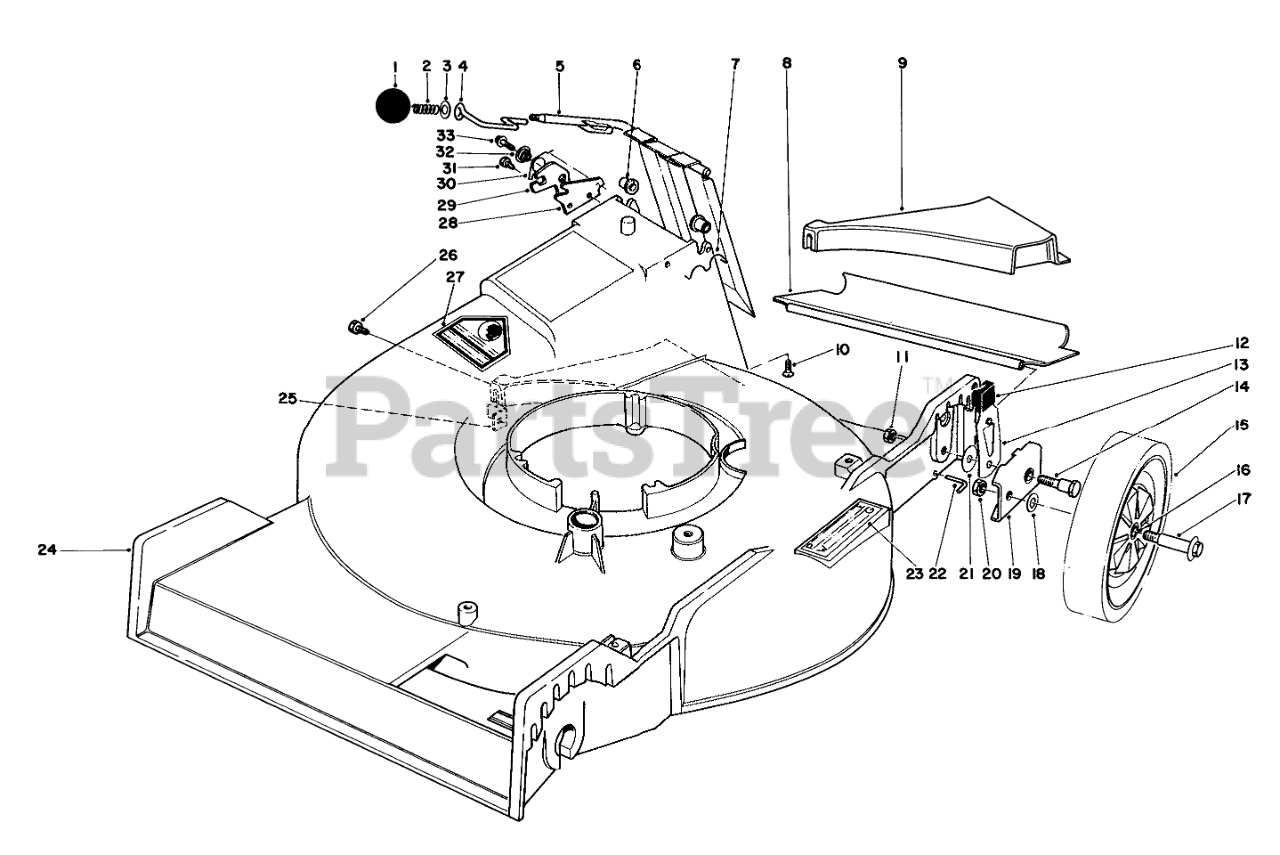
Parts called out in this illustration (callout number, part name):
2	COMPRESSION SPRING
3	WASHER
4	DOOR LATCH
5	DOOR HANDLE WA
6	BUSHING-NYLON
7	DOOR RETAINER
8	REAR SAFETY SHIELD
9	REAR INSERT
10	SCREW-HH
11	NUT-LOCK, NI
12	KNOB-ARM
13	SPRING ARM ASM HP
14	PIVOT SCREW
15	Wheel & Tire Assembly (Incl. Ref. #16)
16	BUSHING
17	BOLT-WHEEL
18	WASHER
19	HP PIVOT ARM ASM
20	Nut
21	PIVOT WASHER
22	ROD-SHIELD
23	Decal-Step Pad
24	Housing (Incl. Ref. #23 & 27)
25	SPECIAL NUT
26	SCREW THD 1/4 20 5/8
27	DECAL-DANGER
28	DOOR LATCH PLATE
29	SAFETY LATCH
30	TORSION SPRING
31	Screw
32	DOOR SPACER
33	SCREW-HWH
